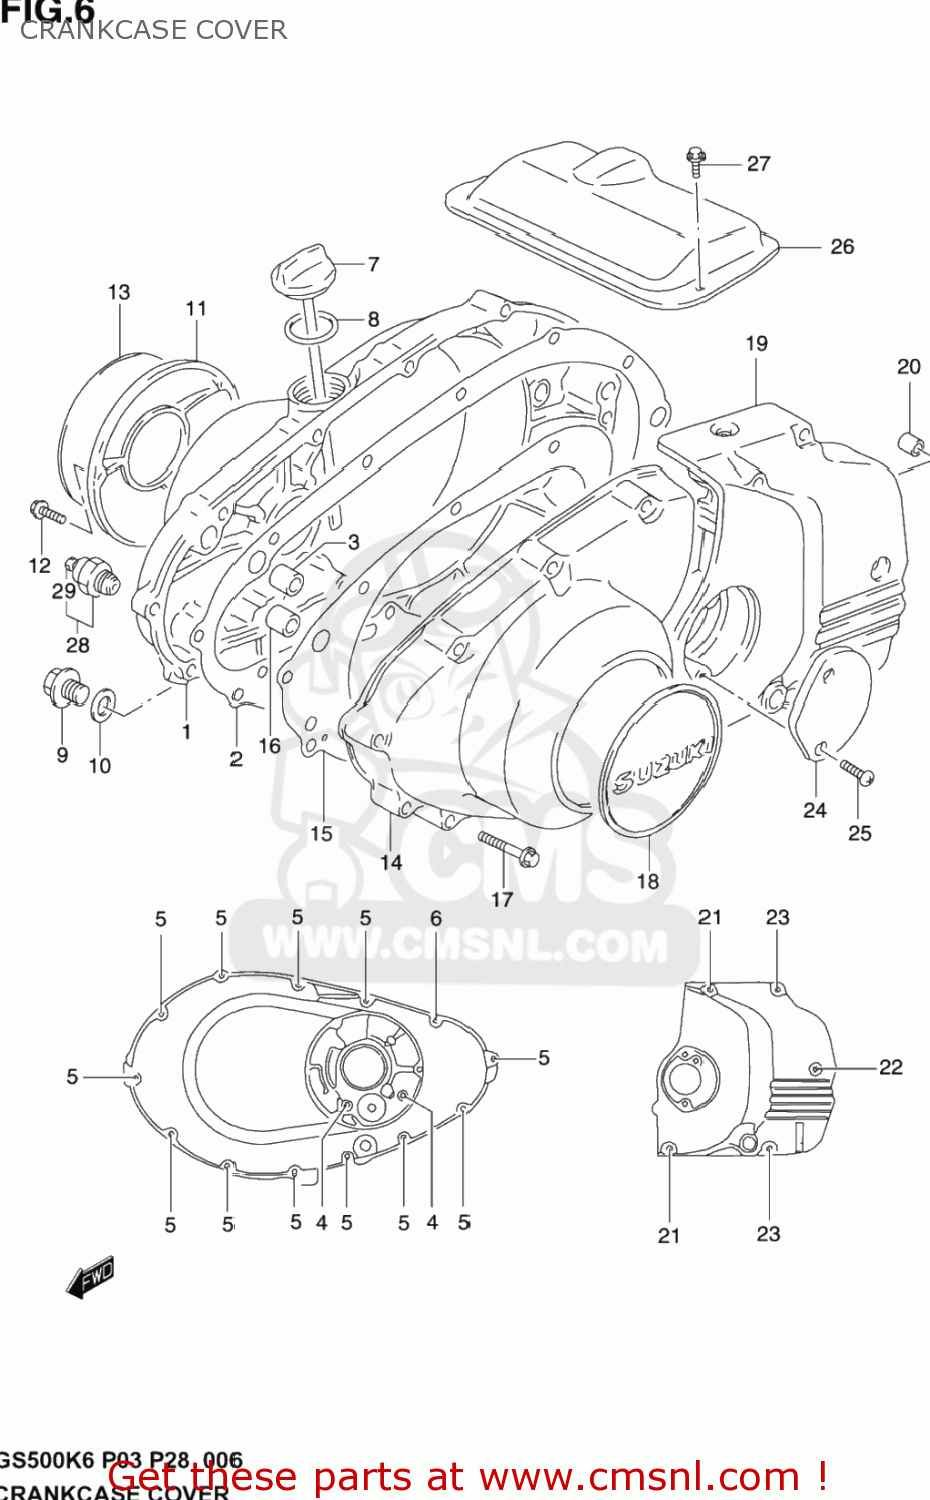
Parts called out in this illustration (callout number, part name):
1	COVER,CLUTCH
2	GASKET,CLUTCH COVER (NAS)
3	PIN
4	BOLT(6X55)
5	BOLT(6X35)
6	BOLT(6X25)
7	GAUGE,OIL LEVEL
8	O RING(D:3.1,ID:26.4)
9	PLUG (14X12)
10	GASKET(13.8X18.8X4.8) (NAS)
11	COVER,CONTACT BREAKER
12	BOLT(5X16)
13	EMBLEM,CONTACT BREAKER COVER
14	COVER,MAGNETO
15	GASKET,MAGNETO COVER (NAS)
16	PIN
17	BOLT(6X35)
18	EMBLEM,CONTACT BREAKER COVER
19	COVER,ENGINE SPROCKET
20	PIN
21	BOLT(6X65)
22	BOLT(6X50)
23	BOLT(6X40)
24	CAP,CLUTCH RELEASE ADJUST
25	SCREW
26	COVER,STARTER MOTOR
27	BOLT
28	SWITCH ASSY,OIL PRESSURE
29	BOLT,OIL PRESSURE SWITCH
